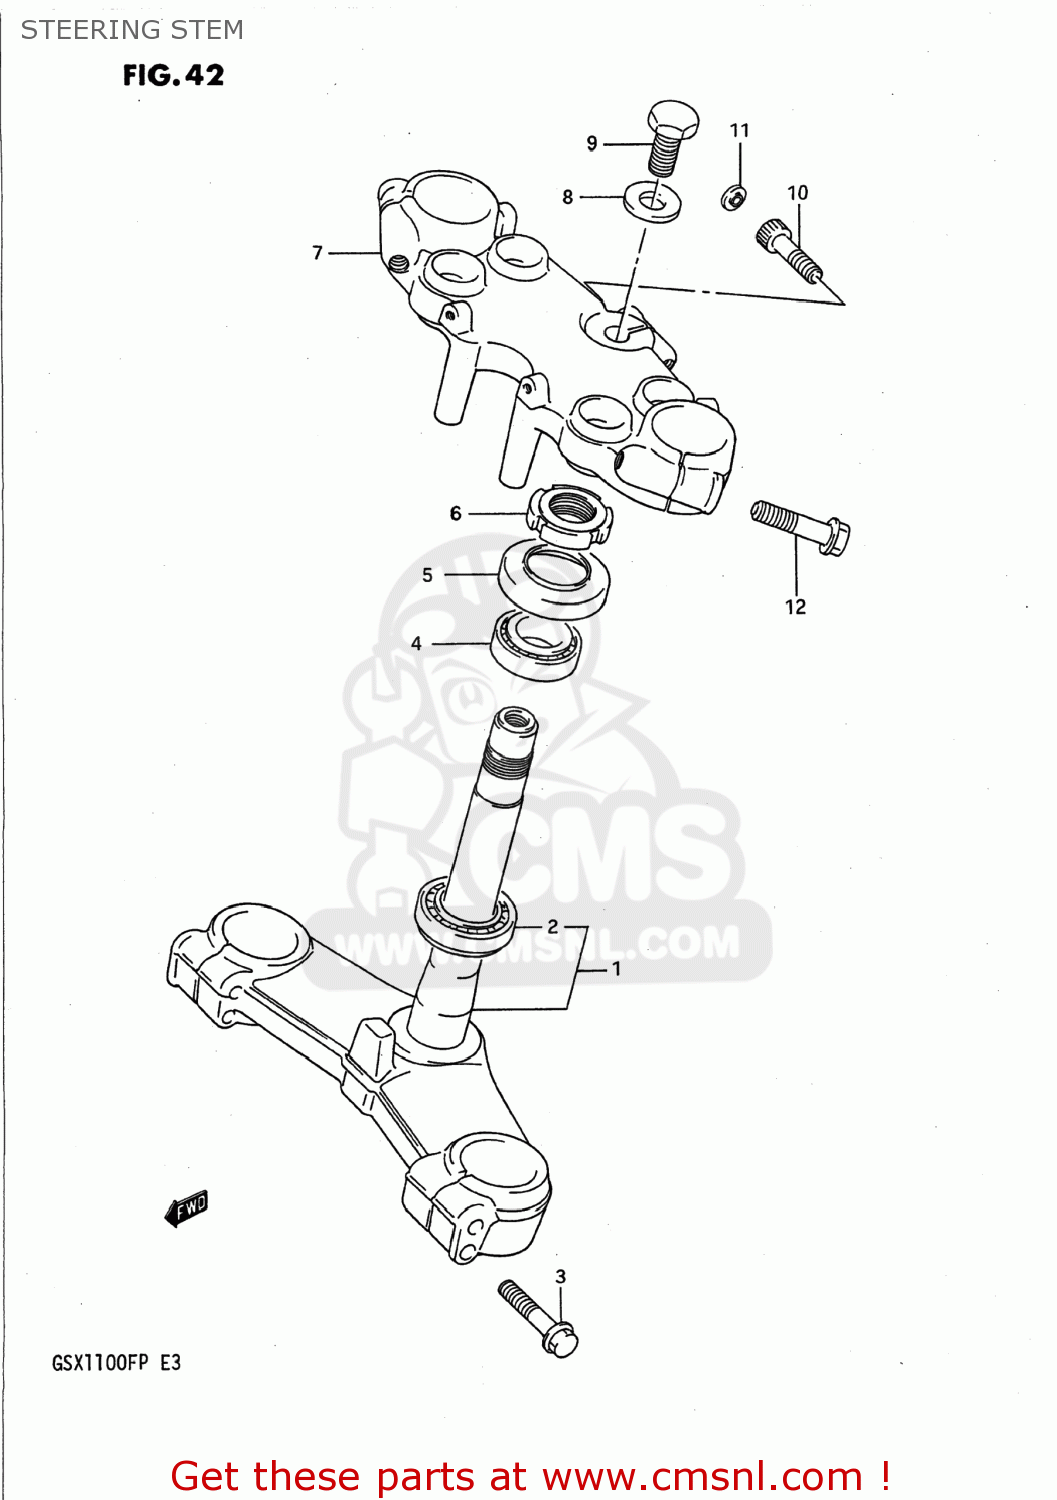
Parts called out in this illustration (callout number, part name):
1	STEM,STEERING
2	BEARING(30X55X17)
3	BOLT
4	TAPER,ROLLER BEARING
5	DUST SEAL,STEERING UPR
6	NUT,STEERING STEM(25X44X10)
7	BRACKET,UPR
8	WASHER,STEM HEAD
9	BOLT
10	BOLT, REAR (8X30)
11	CAP(OD:14.5)
12	BOLT 10X40
